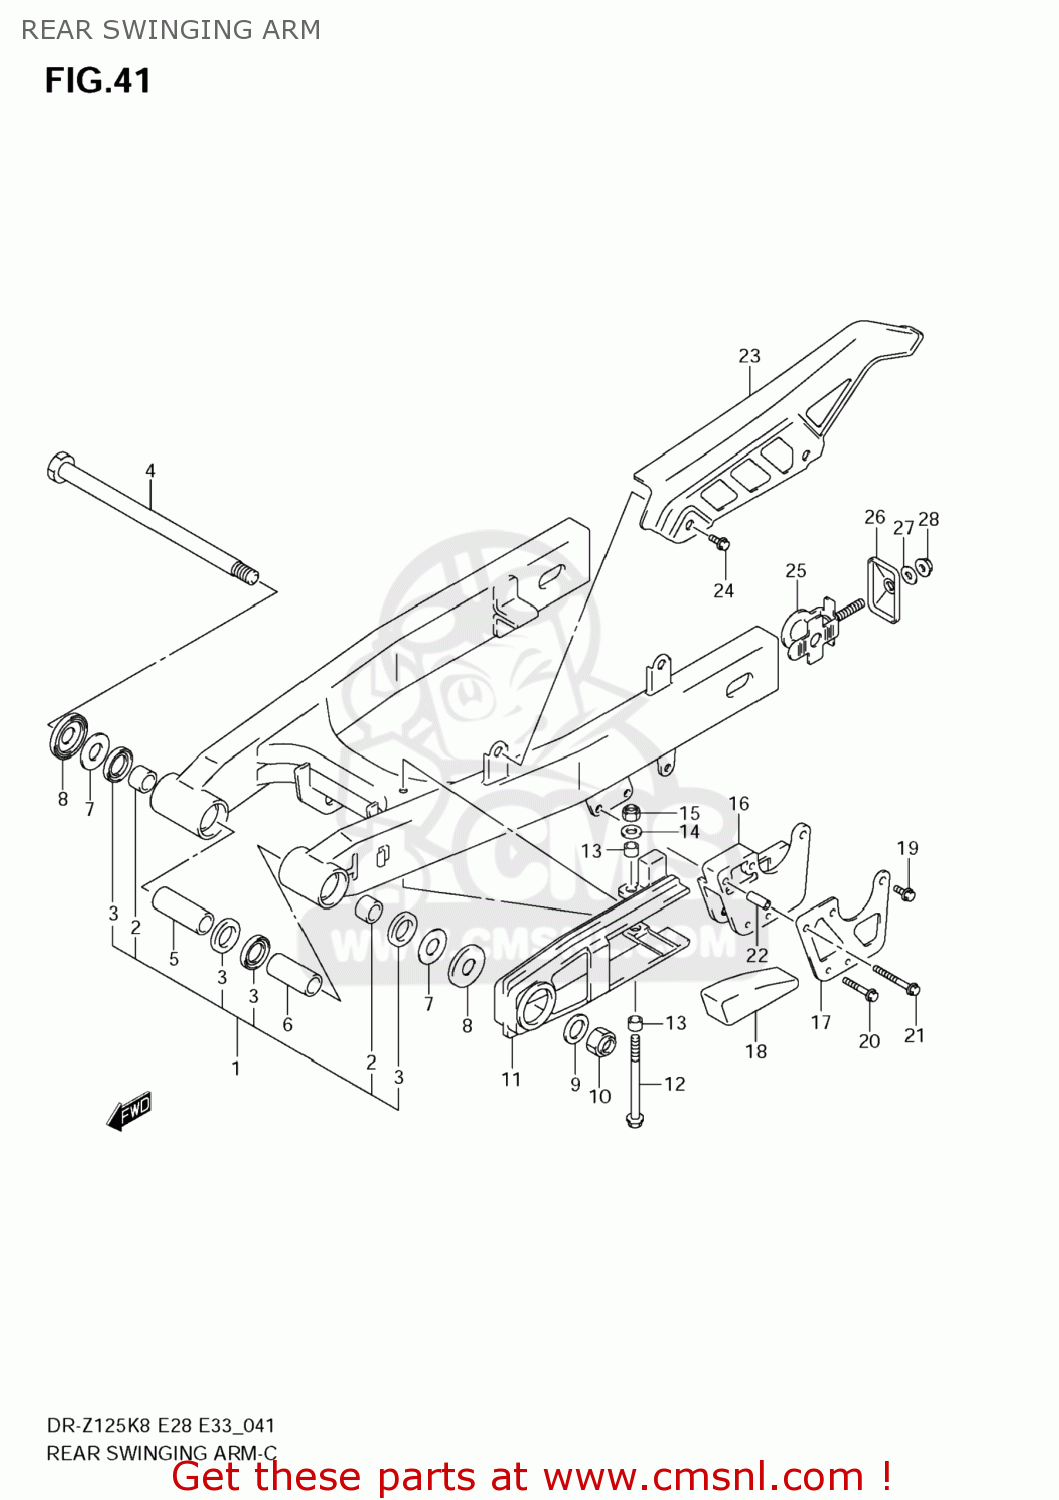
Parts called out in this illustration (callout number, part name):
1	SWINGINGARM ASSY,RR
2	BUSHING,RR SWGARM PIVOT
3	SEAL,OIL(20X27X5)
4	SHAFT,RR SWINGINGARM PIVOT
5	SPACER,RR SWGARM PIVOT,R
6	SPACER,RR SWGARM PVT
7	WASHER
8	COVER,RR SWGARM DUST SEAL
9	WASHER(14.5X24X2.3)
10	NUT
11	BUFFER,CHAIN TOUCH DEFENSE
12	BOLT
13	SPACER(6.5X9X6.5)
14	WASHER
15	NUT
16	GUIDE,CHAIN
17	PLATE,GUIDE CHAIN OUTER
18	DEFENSE,CHAIN GUIDE
19	BOLT(6X16)
20	BOLT(6X40)
21	BOLT(6X30)
22	SPACER(6.5X10X23.5)
23	CASE,CHAIN
24	BOLT(6X10)
25	ADJUSTER,CHAIN
26	PLATE,CHAIN ADJUSTER
27	WASHER(12.5X26X2.3)
28	NUT
